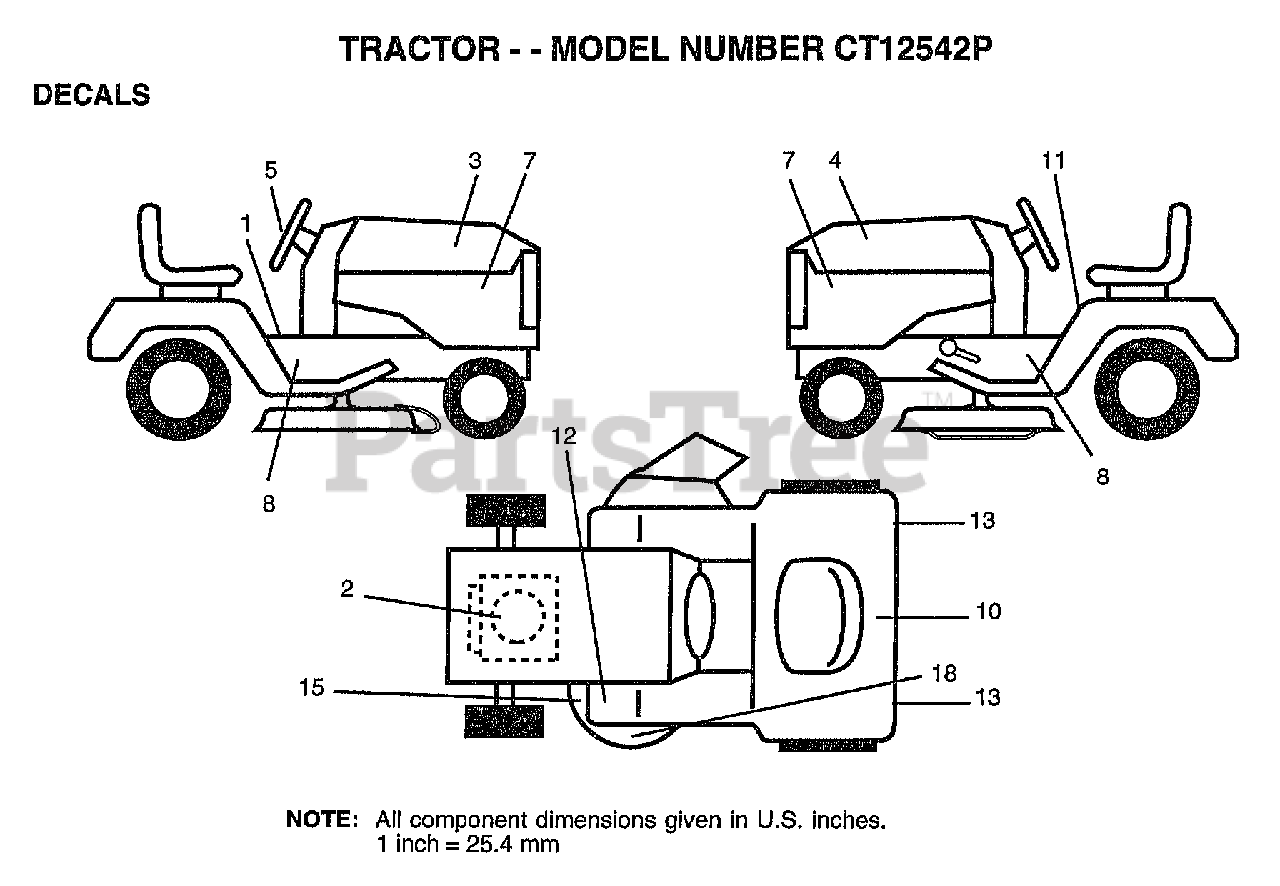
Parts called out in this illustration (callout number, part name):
1	"DECAL DASH,OPER."
2	DECAL, HP ENGINE
3	DECAL HOOD RH
4	"DECAL HOOD,LH"
5	DECAL INST STG WH
7	"DECAL PANEL,SIDE"
8	"DECAL CHASSIS 42"""
10	DECAL.BATRY.3-3908
11	"DECAL DANGER,FEND"
13	REFLECTOR-TAIL YT
15	"DECAL-SCHEM,BELT"
18	"DECAL,ENVIRO DECK"
